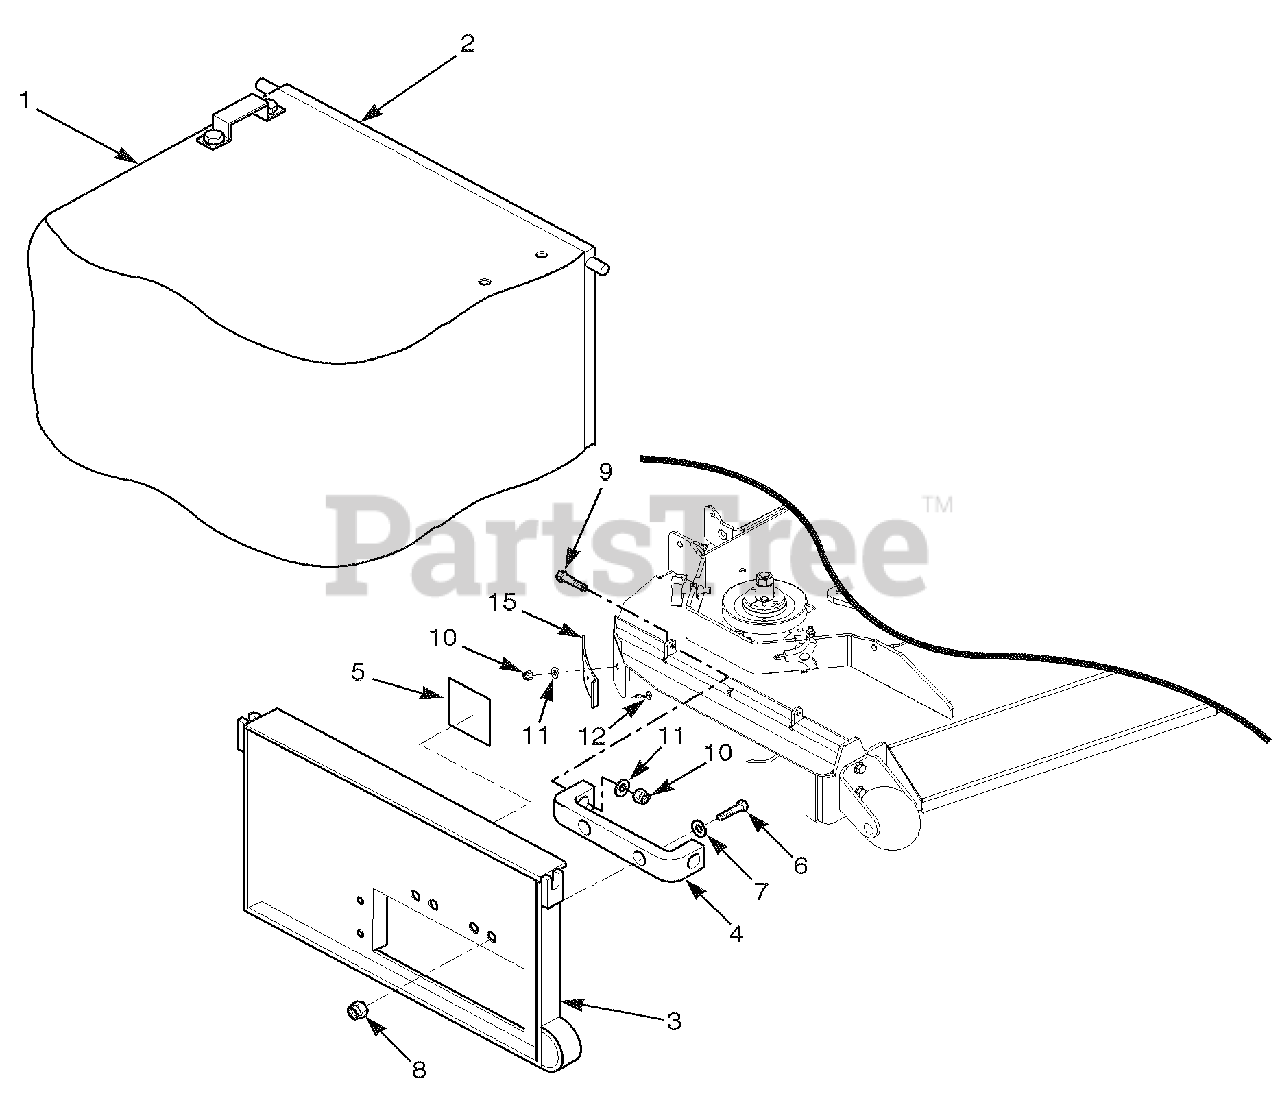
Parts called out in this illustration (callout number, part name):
1	Catcher Bag
2	Frame Weldment With Catcher Bag and Handle Assembly
3	Cover Weldment With Decal
4	Bracket, Mounting
5	Decal, Danger
6	Bolt, 3/8-16 x 1-1/2" Hex Head
7	Flat Washer, 3/8"
8	Nut, 3/8-16 Elastic Stop
9	Bolt, 5/16-18 x 1-1/4" Hex Head
10	Nut, 5/16-18 Elastic Stop
11	Flat Washer, 5/16"
12	Bolt, Carriage 5/16-18 x 3/4"
13	Bolt, Hex Head 1/4-20 x 3/4"
14	Nut, Elastic Stop 1/4-20
15	Filler Plate, Grass Catcher Velocity Plus Decks
